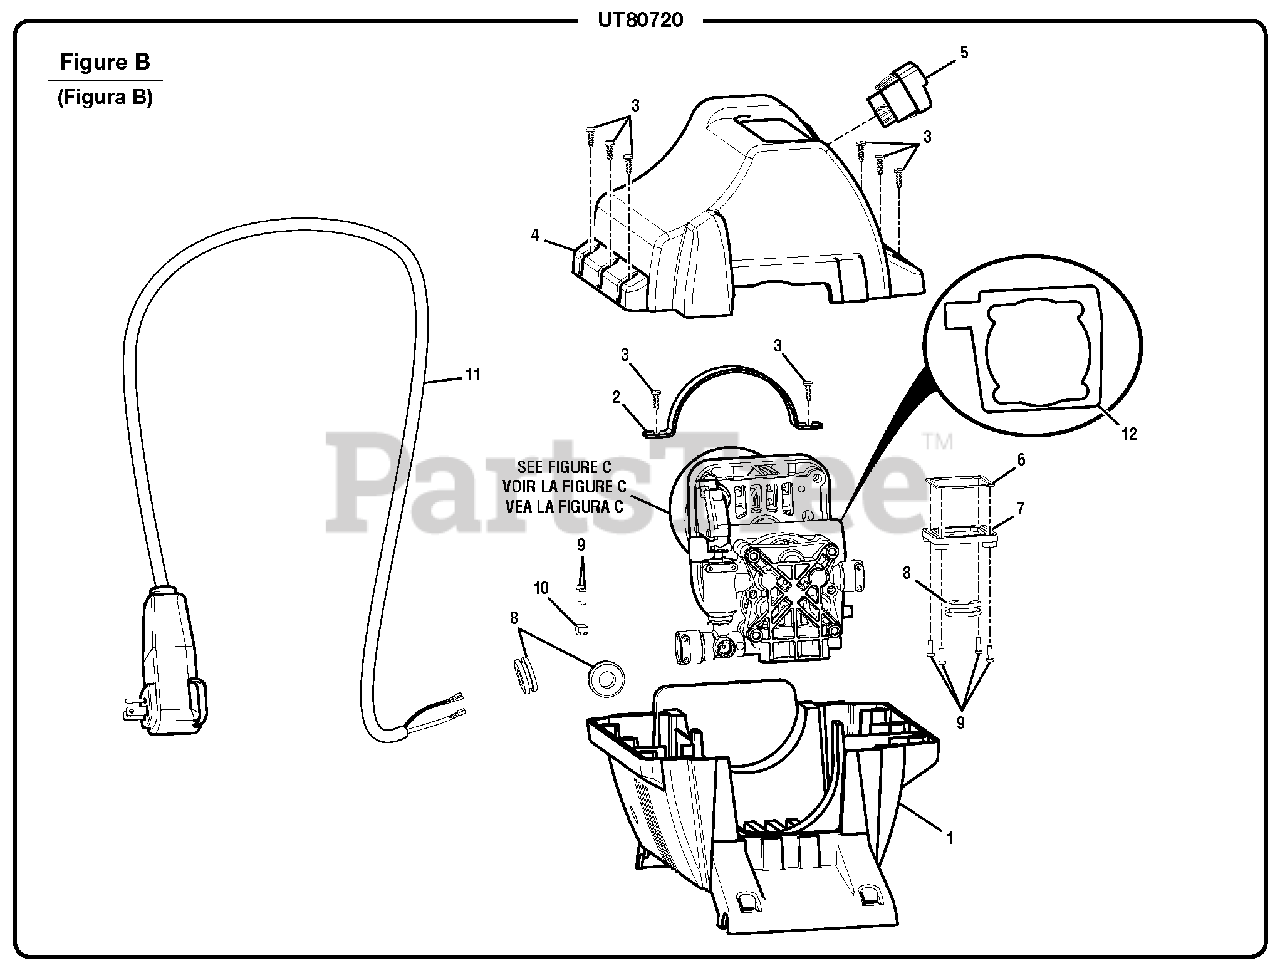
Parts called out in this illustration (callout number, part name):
1	Bottom Motor Housing
3	Screw (M4 x 12 mm, Pan Hd.)
4	Top Motor Housing
6	Switch Cover Gasket
7	Switch Cover
8	Grommet (13 mm)
9	Screw (M3 x 10 mm)
10	Cord Clamp
11	Electrical Cord
